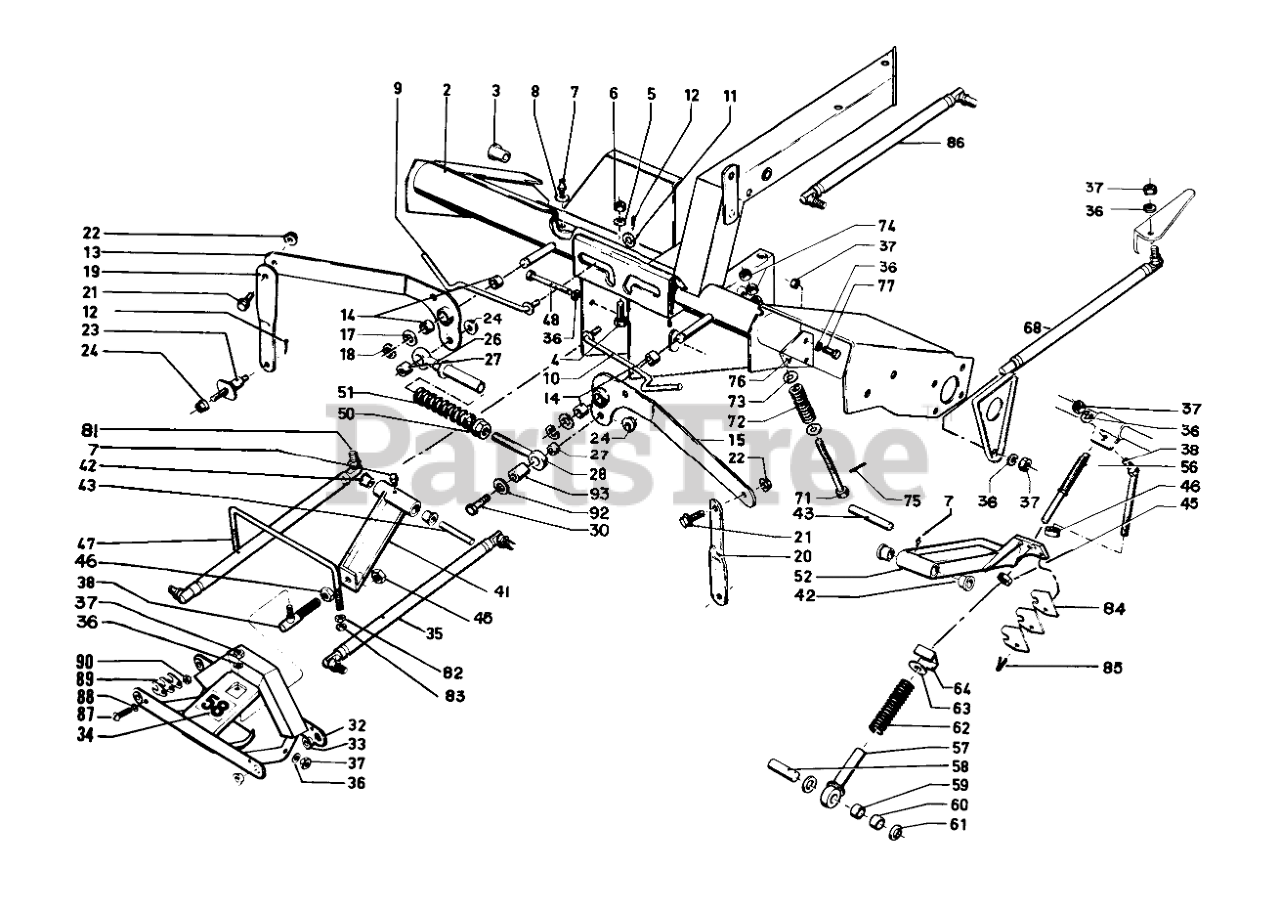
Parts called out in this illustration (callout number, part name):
3	3/4IDX1LG FLANGE BSHG
4	SCREW-HH
5	WASHER-LOCK
6	NUT-HEX
7	FITTING-GREASE
8	WASHER-LOCK
11	WASHER-FLAT
12	PIN-COTTER
14	BUSHING
17	WASHER-FLAT
18	RING-RETAINING, EXTERNAL
21	SHOULDER BOLT
22	NUT-LOCK
27	BUSHING
30	SCREW-HH
33	BUSHING-FLANGE
36	WASHER-LOCK
37	NUT-HEX
38	BALL JOINT
42	BUSHING-FLANGE
45	NUT-JAM
46	NUT-LOCK, NI
48	SCREW-HH
50	NUT-LOCK, FLANGE
56	Anchor
57	GUIDE BUSHING WA
59	SPLIT SPACER
61	WASHER-FLAT
62	COMPRESSION SPRING
64	ADJUSTING NUT
72	SPRING
73	WASHER-FLAT
74	NUT-HEX
75	PIN-ROLL, SLOTTED
76	Anchor Plate
77	SCREW-HH
82	NUT-HEX
85	PIN-COTTER
87	10-24 X 7/8 RND HD MS
88	SPACER
89	FRONT SIDE SHIM
90	NUT-LOCK, NI
92	WASHER-FLAT
